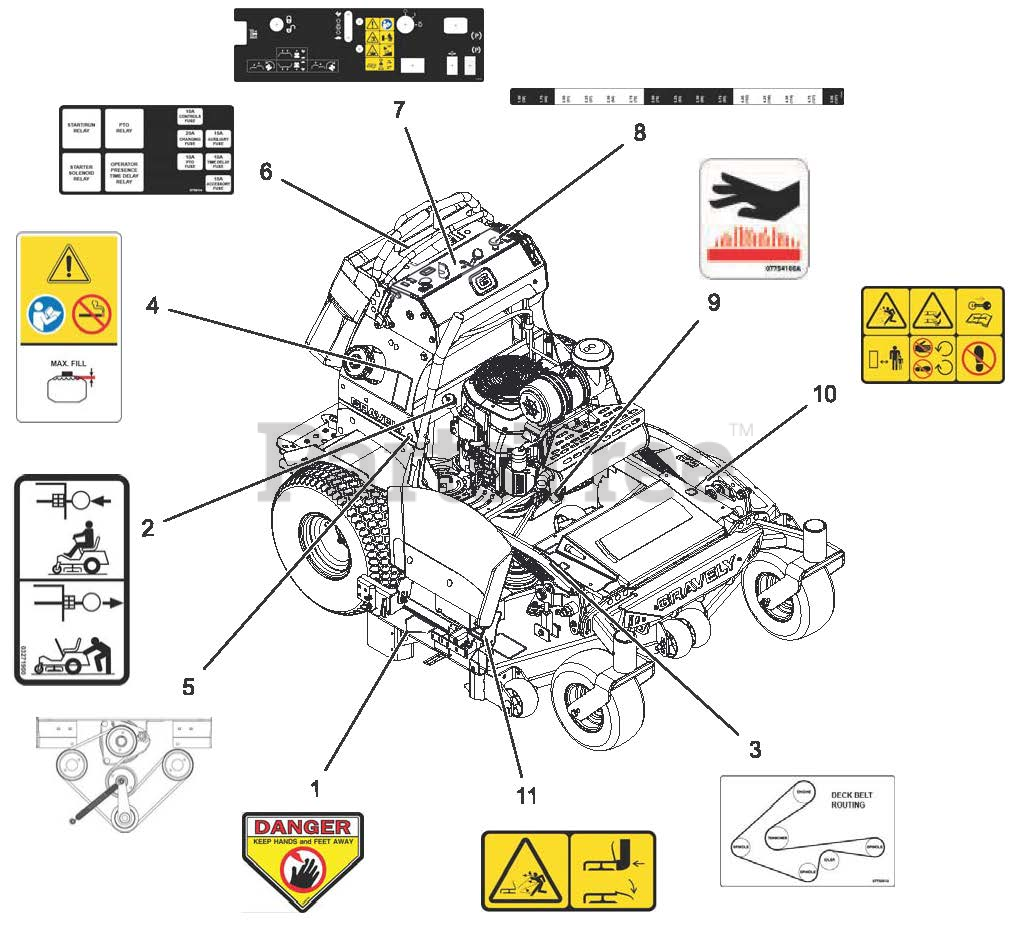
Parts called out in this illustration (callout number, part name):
1	DECAL, DANGER
2	DECAL, TRANSMISSION DISCONNECT
3	DECAL, BELT ROUTING 48/52 REV
4	DECAL, FUEL WARNING
5	DECAL, HYDRO BELT
6	DECAL, FUSE BLOCK
7	DECAL, CONTROL PANEL
8	DECAL, HOC DIAL
9	DECAL, HOT SURFACE
10	DECAL, SAFETY - MOWER DECK
11	DECAL, SAFETY - DECK GUARDING
